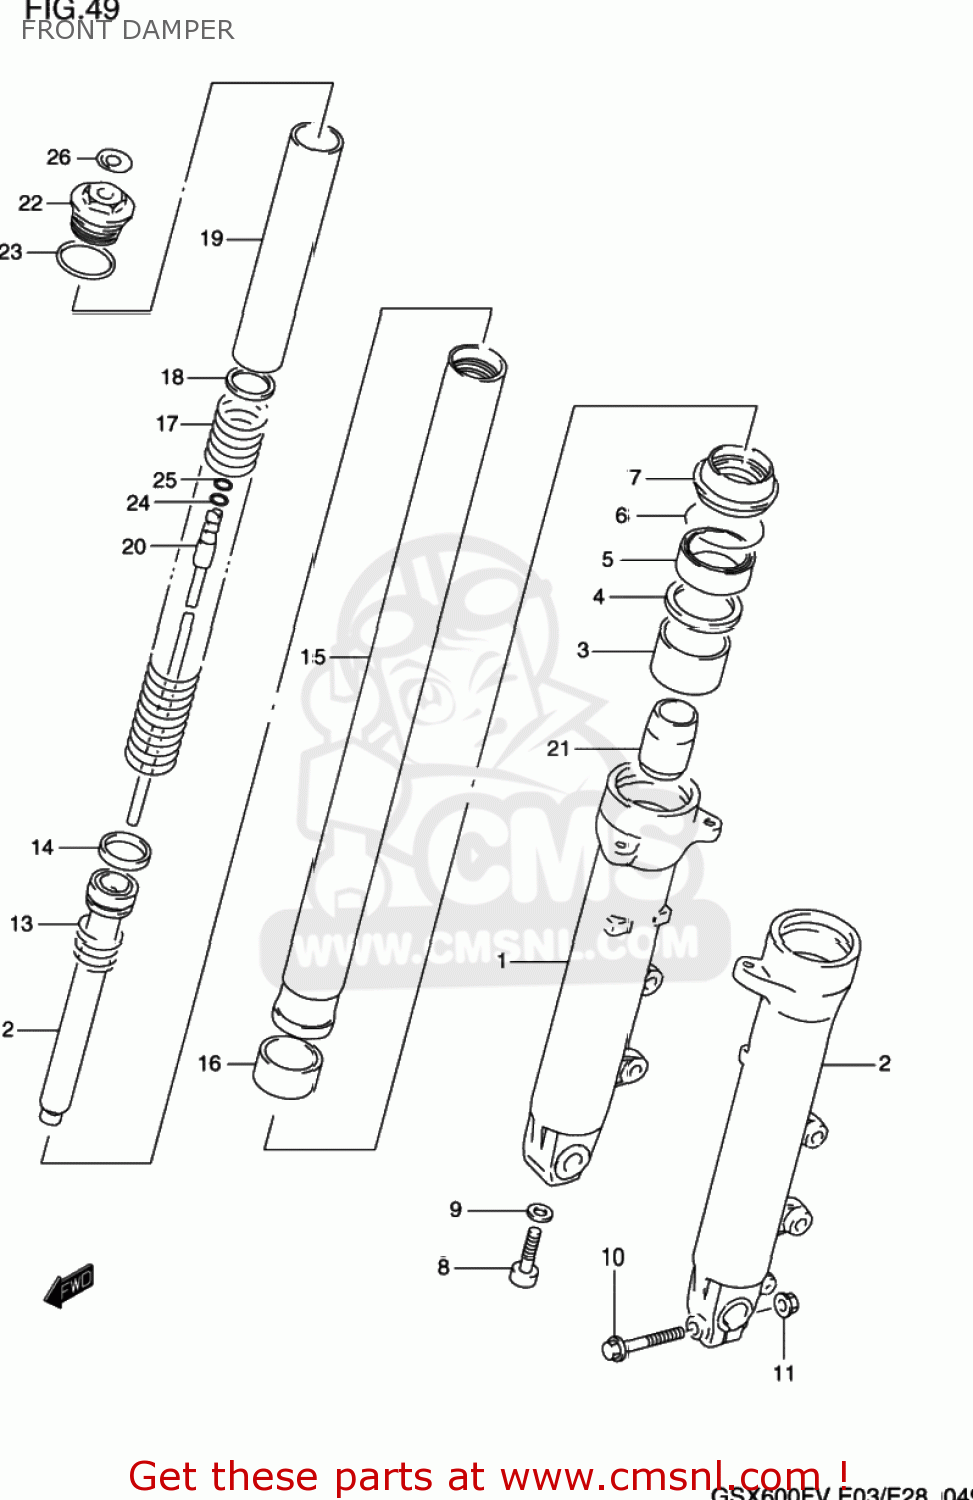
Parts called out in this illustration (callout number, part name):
1	TUBE,OUTER,RIGHT
2	TUBE,OUTER,L
3	BUSH,GUIDE
4	SPACER,SEAL
5	SEAL,OIL
6	CIRCLIP,FORK OIL SEAL
7	SEAL,DUST
8	BOLT(8X27)
9	GASKET (NAS)
10	BOLT
11	NUT
12	PIPE,SEAT UNDER
13	SPRING,REBOUND
14	RING,PISTON
15	TUBE,INNER
16	BUSH,SLIDE
17	SPRING,FRONT
18	JOINT,SPRING
19	SPACER,SPRING
20	ROD,INNER
21	PIECE,OIL LOCK
22	BOLT,FORK
23	O RING
24	O RING(D:1.9,ID:5.7)
25	RING,STOPPER(ID:6.1,D:0.6)
26	LABEL,S-H
